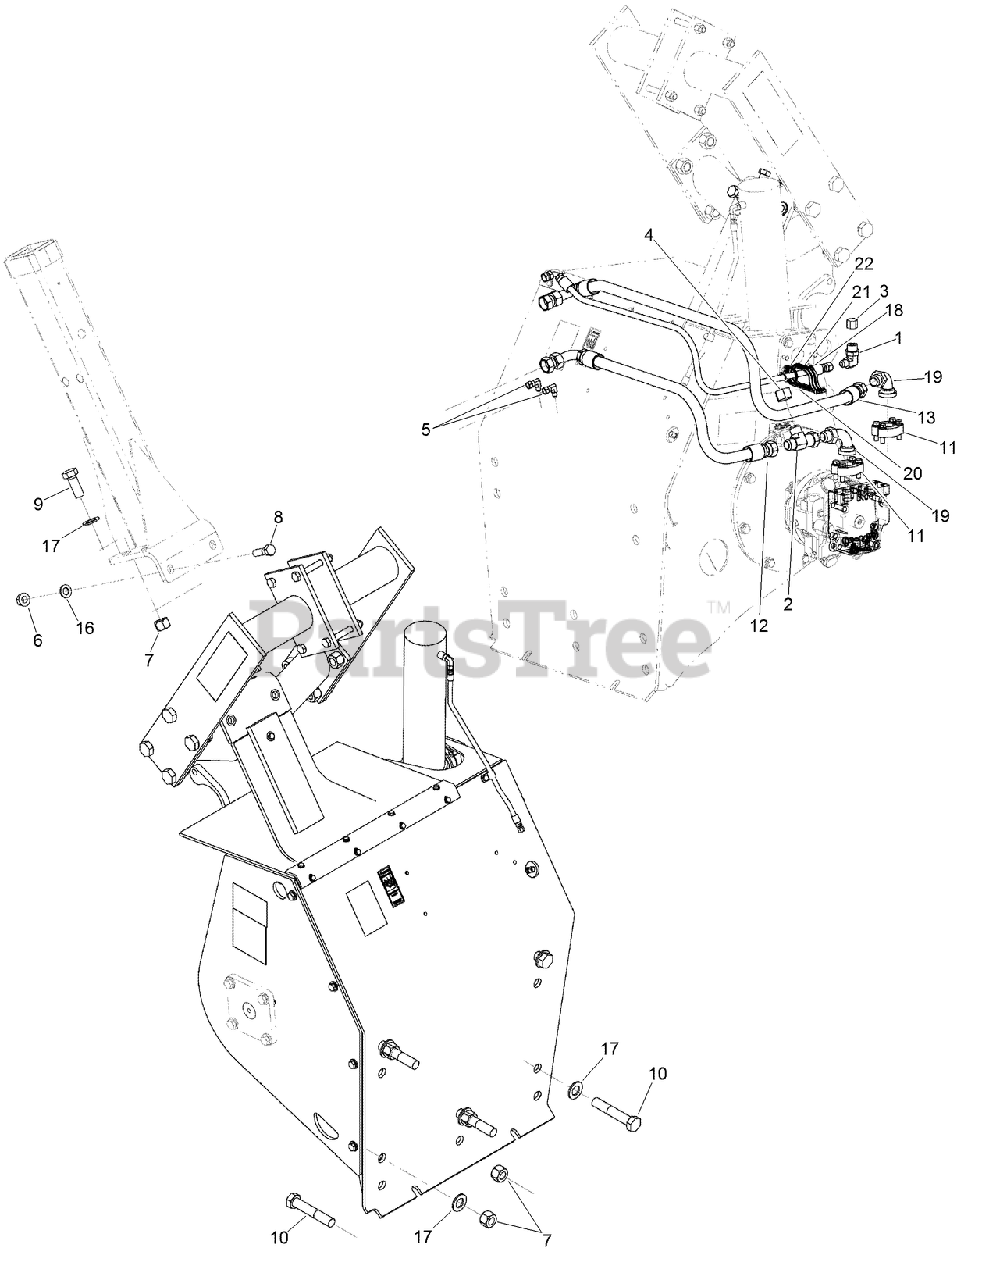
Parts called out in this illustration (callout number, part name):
1	ADAPTOR-ELBOW
2	TEE-SWIVEL
3	FITTING-CAP
5	ELBOW-SWIVEL, 90 DEG
6	NUT-HEX FLANGE
10	BOLT - Hex Hd 1.00 x 5.50 GR8 ZND
11	HYD FLANGE KIT
12	ASSEMBLY - Hose, Low Pressure Loop
13	ASSEMBLY - Hose, Low Pressure Loop
16	WASHER-Flat
18	HOSE - 2100 mm (82-11/16 inch) Long, 2100 mm Long, Control Valve to Trencher Drive Motor
19	FITTING-ELBOW
20	STRAP-TIE
21	STRAP-TIE
22	STRAP-TIE, NYLON
